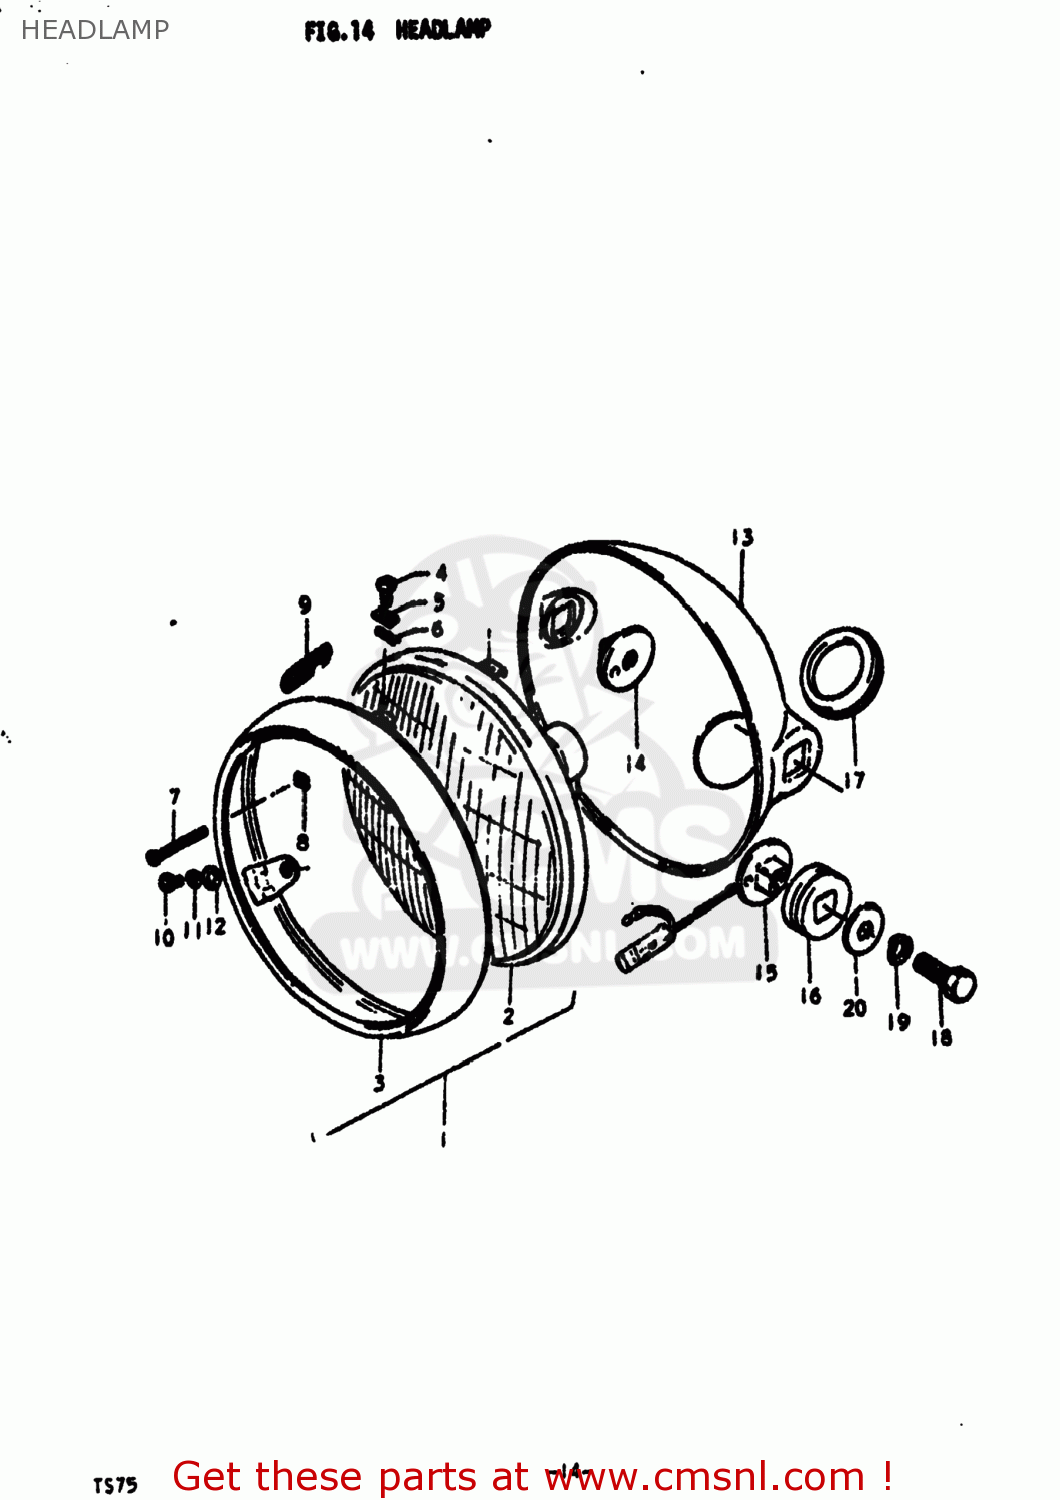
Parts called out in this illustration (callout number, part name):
1	HEADLAMP ASSEMBLY
2	LAMP UNIT
3	RIM,HEADLAMP
4	SCREW
5	NUT,ADJUSTING
6	CUSHION,HEADLAMP
7	SCREW,HEADLAMP ADJUST
8	NUT,HEADLAMP ADJUSTER
9	SPRING,HEADLAMP ADJUST
10	SCREW
11	LOCK WASHER
12	WASHER
13	HOUSING COMP,HEADLAMP
14	SPACER, HOUSING RH
15	SPACER, HOUSING LH
16	CUSHION,HEADLAMP HOUSING
17	GROMMET,HEADLAMP HOUSING
18	BOLT
19	LOCK WASHER
20	WASHER
